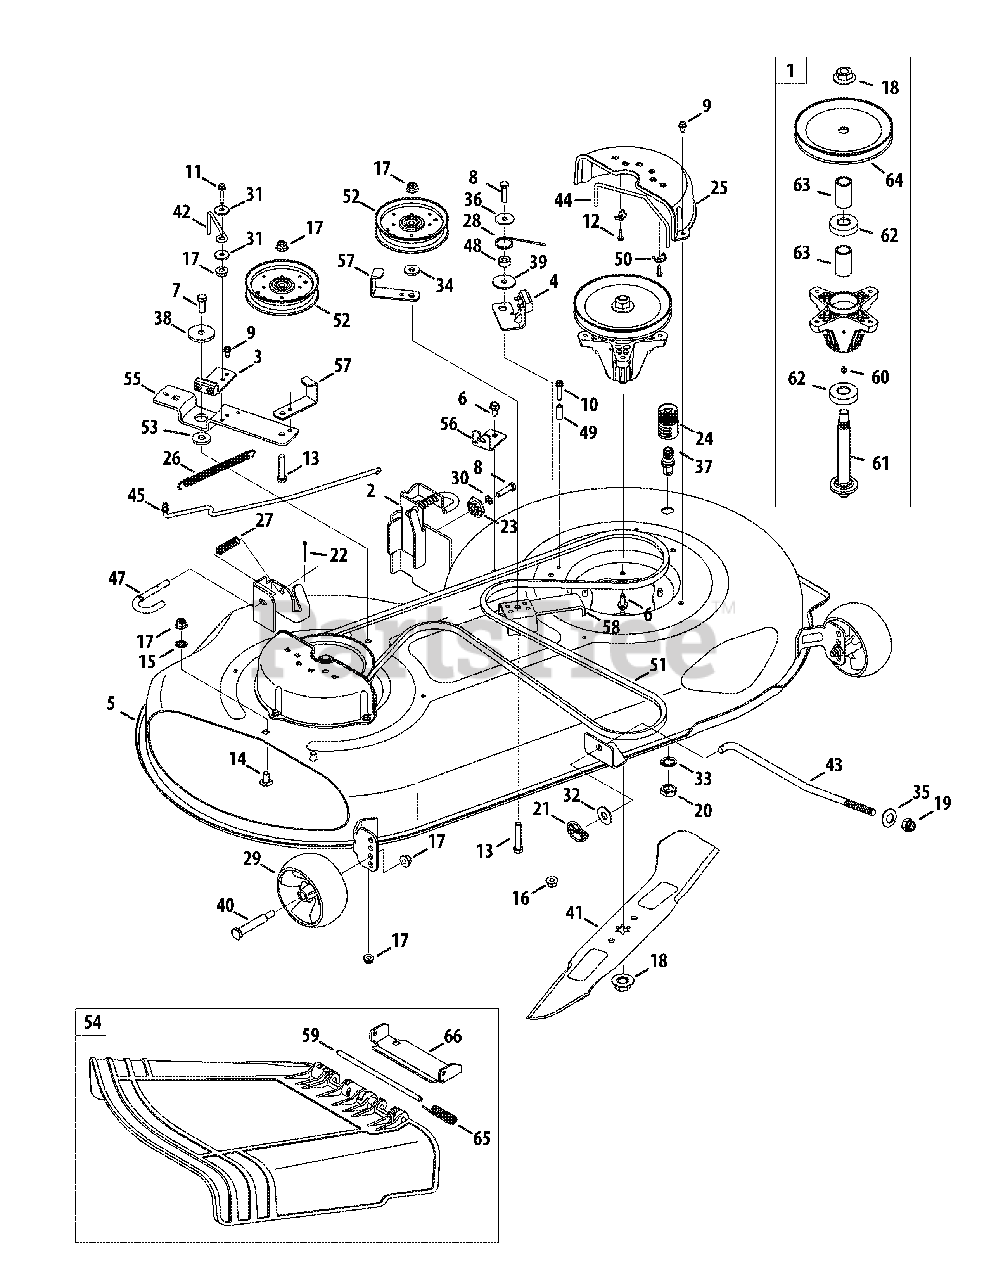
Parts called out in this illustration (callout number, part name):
1	Spindle Ass’y, Pulley 6.93 Dia
2	Bracket Ass’y, Deck, Hanger LH Lt
3	Brake Ass’y, Deck, 42/46
4	Brake Ass’y, Deck, 46"
5	Deck Ass’y, Offset, 46"
6	Screw, Self-tapping, 5/16-18, .750,
7	Hex Screw, 3/8-16, 1.00, Gr5, Std
8	Hex Screw, 5/16-18, 1.25, Gr5, Std
9	Screw, Self-tapping, 1/4-20, 0.500,
10	Screw, Self-tapping, 1/4-20, 1.500,
11	Screw, Self-tapping, 1/4-20, 1.250,
12	Screw, B, #10-16, 0.625, , Sp
13	Hex Screw, 3/8-16, 2.00, Gr5, Std
14	Bolt, Carriage, 3/8-16, 0.75, Gr1
15	Nut, Push, 3/8
16	Nut, Flange Lock, 5/16-18, Grf,
17	Nut, Flange Lock, 3/8-16, Grf,
18	Nut, Flange, 5/8-18
19	Nut, Lock, 1/2-13
20	Nut, Hex, M16-1.5 Din 936
21	Pin, Lynch, .1875
22	Pin, Cotter, 1/8 x 1.25
23	Gear, Deck, Adjustment
24	Adapter, Water Port
25	Cover, Belt, Universal
26	Spring, Extension, .62 Dia x 6.12
27	Spring, Comp, .535 OD x 1.751
28	Spring, Torsion, .992 I.D x 1.17 O.D
29	Wheel, Deck, 5.0 Dia Ball
30	Washer, Lock, 5/16, Regular Duty
31	Washer, Flat, .265 x .938 x .120
32	Washer, Flat, .531 x 1.25 x .100
33	Washer, Lock, 5/8, Int Tooth
34	Washer, Flat, .385 x .870 x .092
35	Washer, Bell, .63 x 1.25 x .18
36	Washer, Flat, .330 x 1.25 x .06,
37	Port, Water
38	Spacer, Shoulder, .8840 x .190
39	Spacer, Shoulder, .500 x .1475
40	Bolt, Shoulder, .496 x 2.50, 3/8-16
41	Blade, Cut, 23.25" 2-In-1, Econ
42	Rod, Keepr, Belt 42 Idler
43	Rod, Lift, Deck, Frt, 13.7
44	Rod, Keeper, Belt
45	Rod, Control, Brake 46"
46	Rod, Keeper
47	Rod, Handle, Deck Release
48	Spacer, .315 x .750 x .375
49	Spacer, .260 x .375 x 1.030
50	Clamp, Casing
51	Belt, V-Type
52	Pulley, Idler, 4.25"Dia
53	Washer, Flat, .385 x 1.0 x .030
54	Chute Ass’y, Deflector, 46" Offset
55	Bracket, Idler, Pivot, 46
56	Bracket, Cable, Deck Engage
57	Bracket, Guard, Belt, 4.25 Pulley
58	Bracket, Support, Stationary Idler
59	Pin, Hinge, Dia .3125 x 7.96
60	Fitting, 3/16, Lnc#70, Drive Lube
61	Shift, Spindle, 6.11.
62	Bearing, Ball, .787id x 1.85 Odx.551
63	Spacer, .792 x 1.060 x 1.860
64	Pulley, Deck, 6.93 Dia
65	Spring, Torsion, .44 I.D. x 2.0
66	Bracket, Chute, 46
